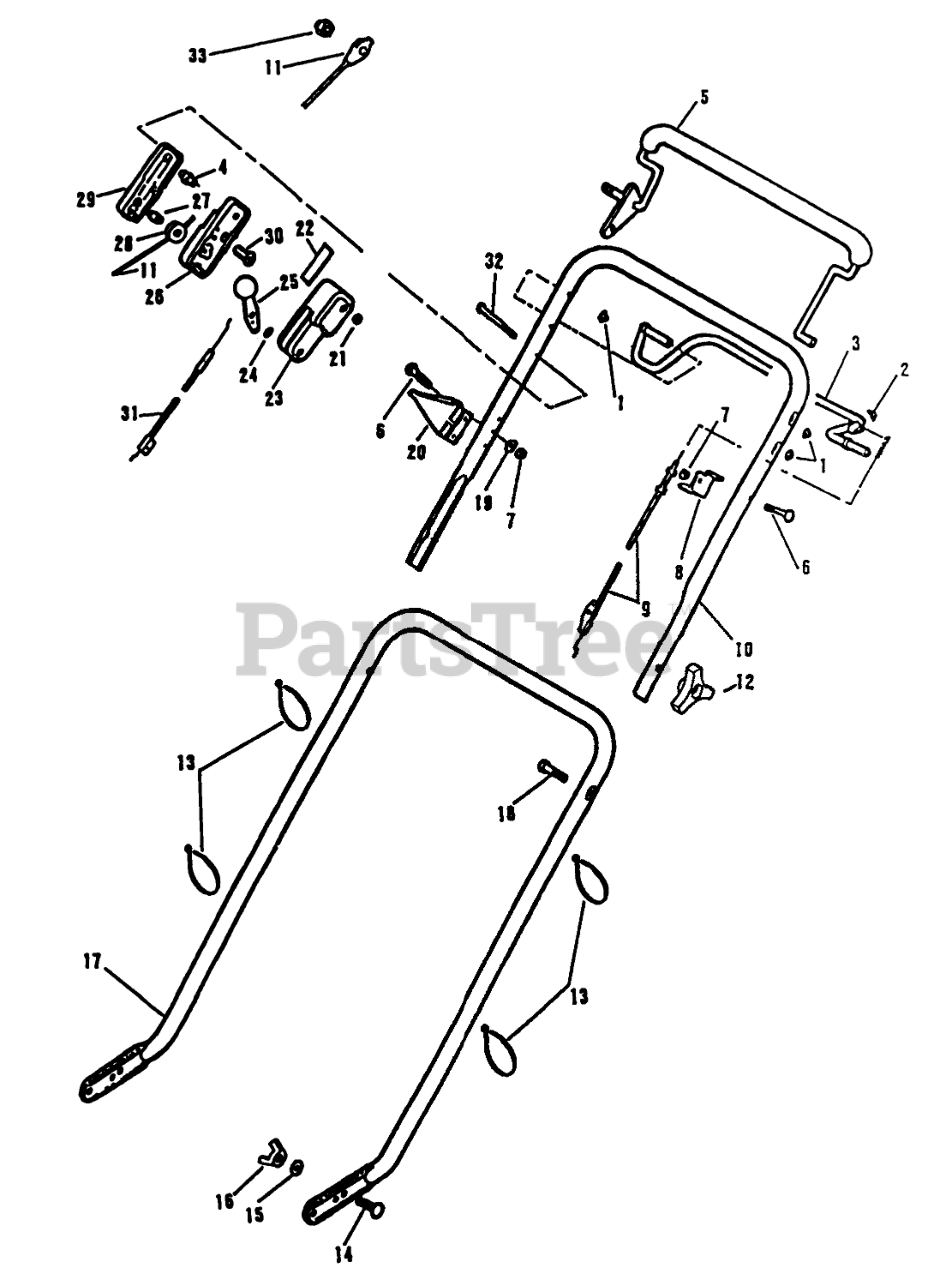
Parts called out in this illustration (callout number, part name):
1	NUT-PUSH
2	NUT
3	CONTROL LEVER AY.
4	COLUMN
5	CONTROL LEVER ARG
6	SCREW
7	LOCKNUT E
8	ANCHOR C'DUIT TRO
9	CABLE - CONTROL
10	Handle-Top
11	CONTROL CABLE
12	Knob
13	TIE-CABLE
14	Bolt
15	WASHER LOCK B'GER
16	NUT WING
17	HDLE-LOWER(GREEN
18	Screw
19	WASHER
20	GUIDE - ROPE
21	NUT C/LOCK E
22	DECAL-THROT CONTRL
23	INNER CONTROL CASE
24	WASHER-SPRING
25	LEVER&KNOB AY WES
26	CENTER CONTROL CASE
27	PIN SKF
28	PULLEY PL
29	OUTER CONTROL CASE
30	SCREW
31	CABLE TH'TTLE WES
32	SCREW
33	NUT ACORN
